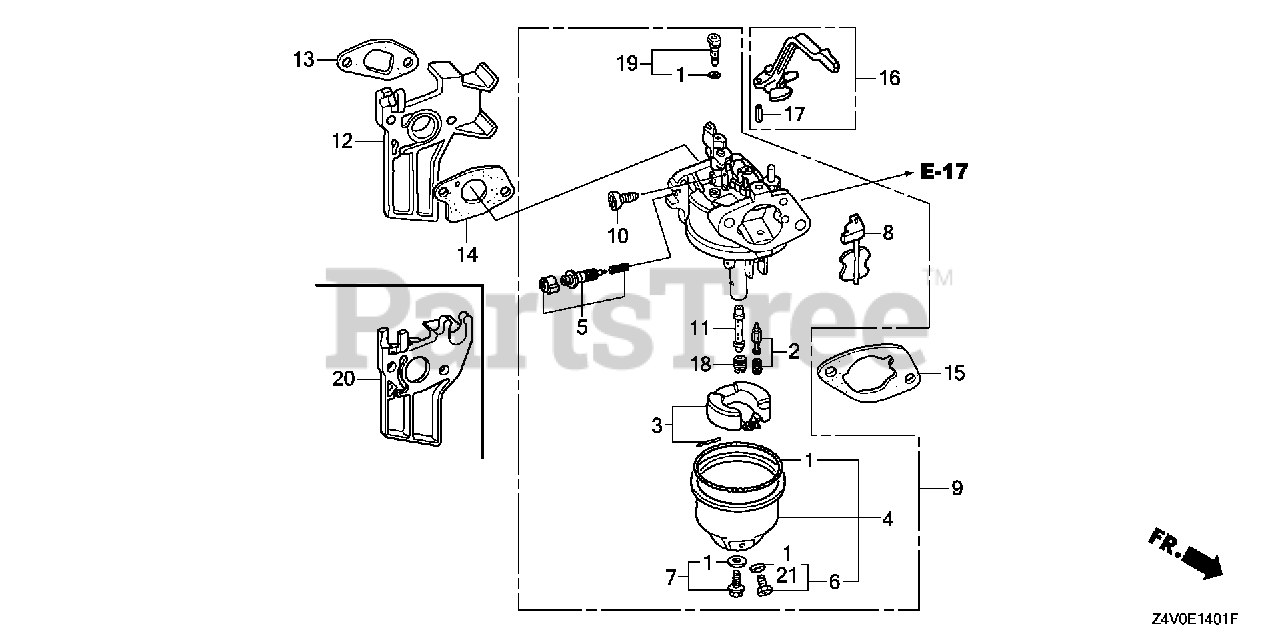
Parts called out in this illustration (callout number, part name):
1	GASKET SET
2	VALVE SET, FLOAT (SEAT NOT INCLUDED)
4	CHAMBER SET, FLOAT
5	SCREW SET, PILOT
6	SCREW SET, DRAIN
7	SCREW SET
9	CARBURETOR ASSY. (BE74K B)
9	CARBURETOR ASSY. (BE74Q A)
10	SCREW, THROTTLE STOP
11	NOZZLE, MAIN
12	INSULATOR, CARBURETOR
13	GASKET, INSULATOR
14	GASKET, CARBURETOR
15	GASKET, AIR CLEANER
16	LEVER, CHOKE
17	PIN, SPRING (2X12)
18	JET, MAIN (#72)
18	JET, MAIN (#75)
18	JET, MAIN (#78)
19	JET SET, PILOT (#40)
21	WASHER, PLAIN (6.2X10.7 DRAIN)
